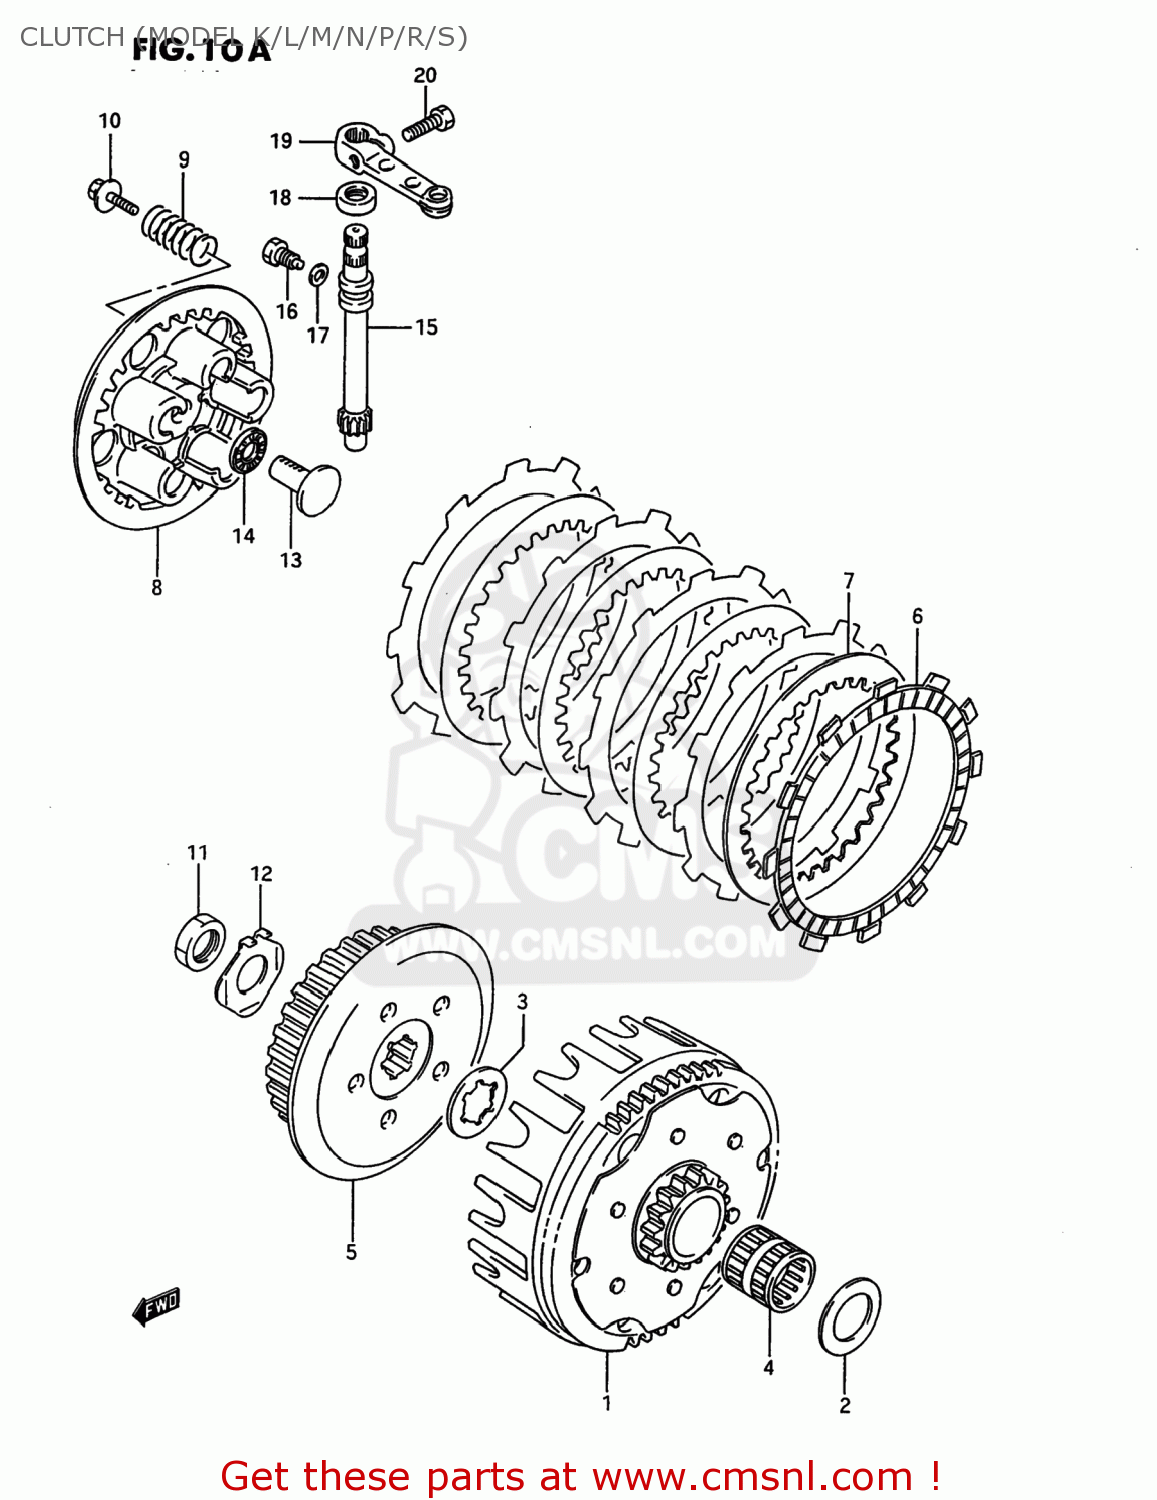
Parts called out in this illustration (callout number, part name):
1	GEAR ASSY,PRI DRIVEN(NT:62/16)
2	WASHER,THRUST
3	WASHER,LOCK
4	BEARING(20X25X26)
5	HUB COMP,CLUTCH SLEEVE
6	PLATE,CLUTCH DRIVE(T:3.0) (NAS)
7	PLATE,CLUTCH DRIVEN(T:2.0) (NAS)
8	DISC,CLUTCH PRESSURE
9	SPRING
10	BOLT 5X16
11	NUT
12	WASHER
13	RACK,CLUTCH RELEASE
14	BEARING(10X22X2.8)
15	PINION,CLUTCH RELEASE
16	BOLT
17	GASKET(6.2X11X1).2 (NAS)
18	SEAL,OIL(10X17X5)
19	ARM,CLUTCH RELEASE
20	BOLT
